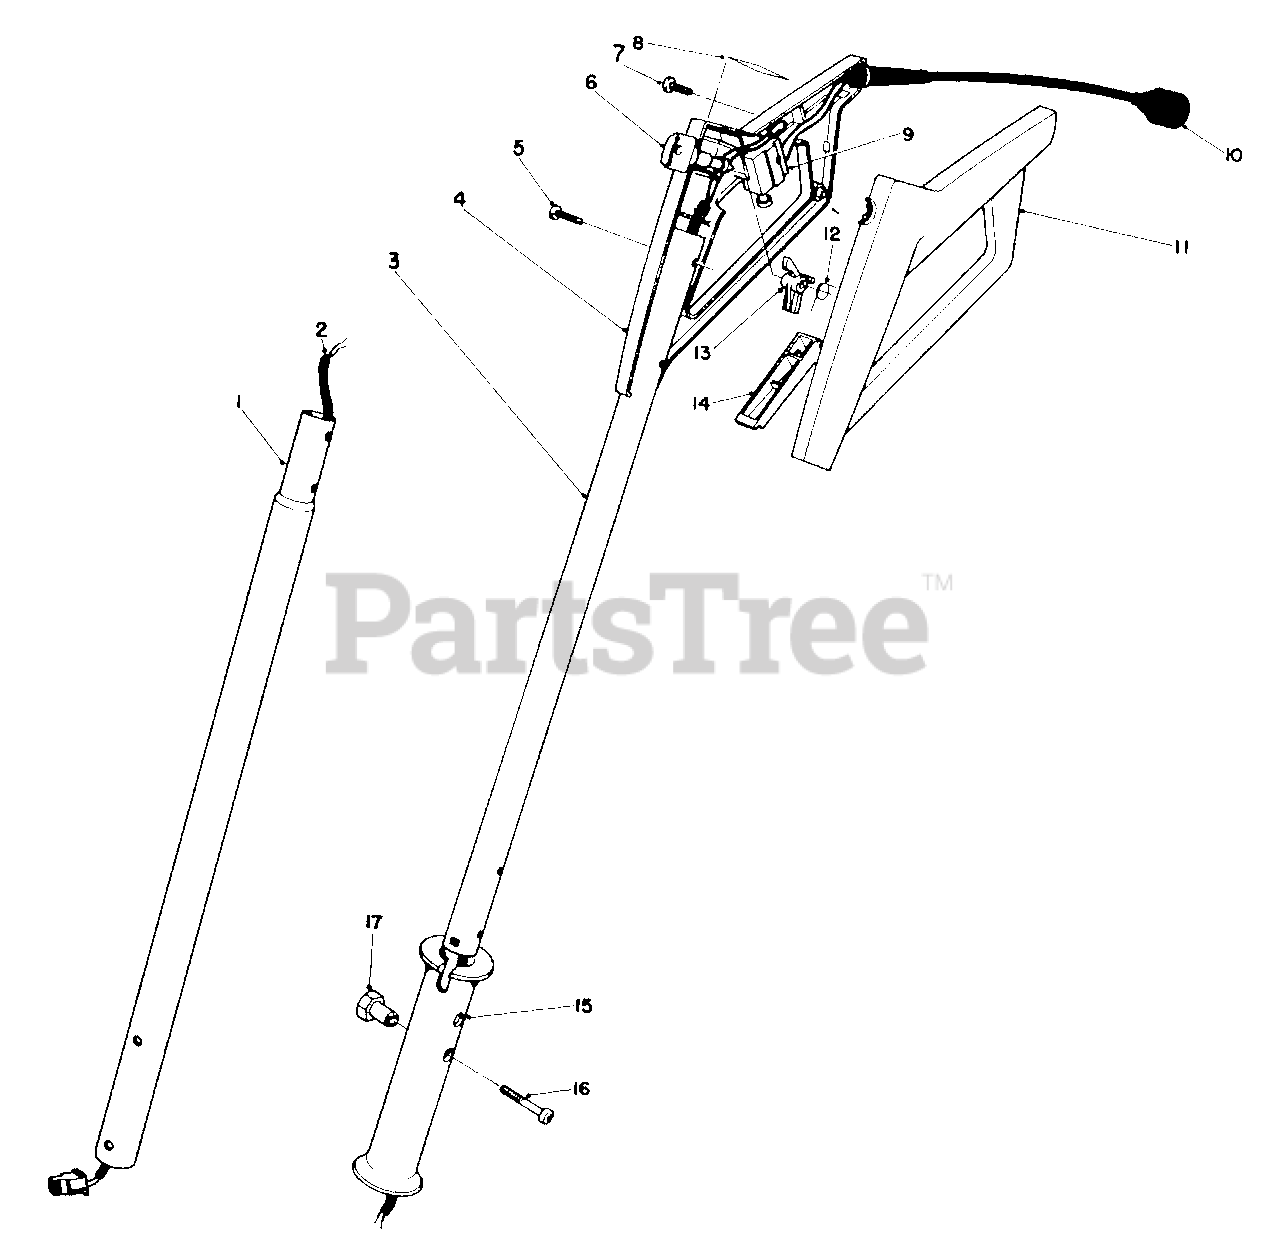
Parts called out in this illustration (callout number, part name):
1	Tube-Lower Handle
2	Wire Harness
3	Tube-Upper Handle
4	Grip-Control R.H.
5	Screw, Pan Head
7	Screw, Pan Head
8	Decal-Control Grip
10	Cord-Supply
11	Grip-Control, L.H.
14	Switch Bar
15	Grip-Handle
16	Screw-Pan Head Special
17	Nut-Hex Special
